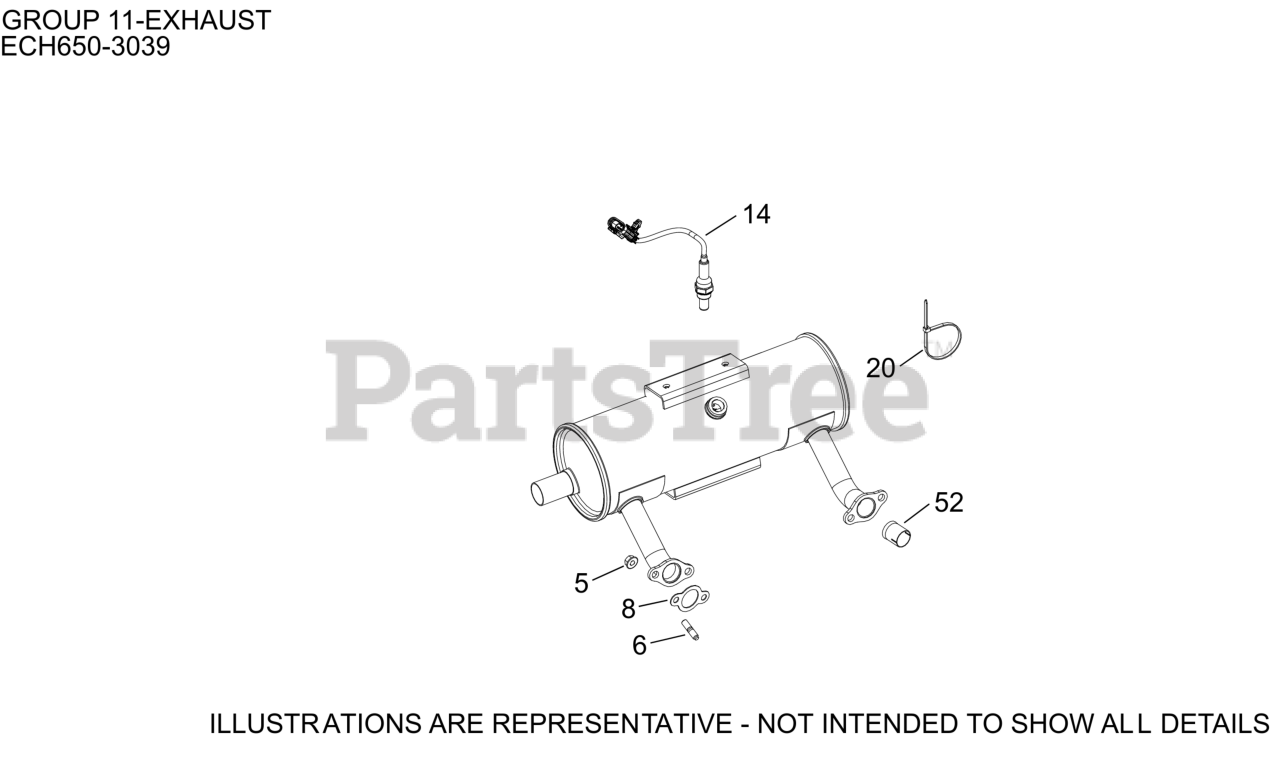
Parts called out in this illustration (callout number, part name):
5	NUT, HEX FLANGE LOCK (M8)
6	STUD, METRIC EXHAUST
8	GASKET, EXHAUST-(#2504117S)
14	SENSOR, OXYGEN (M18 x 1.5 THREADS)
52	LINER, EXHAUST PORT
